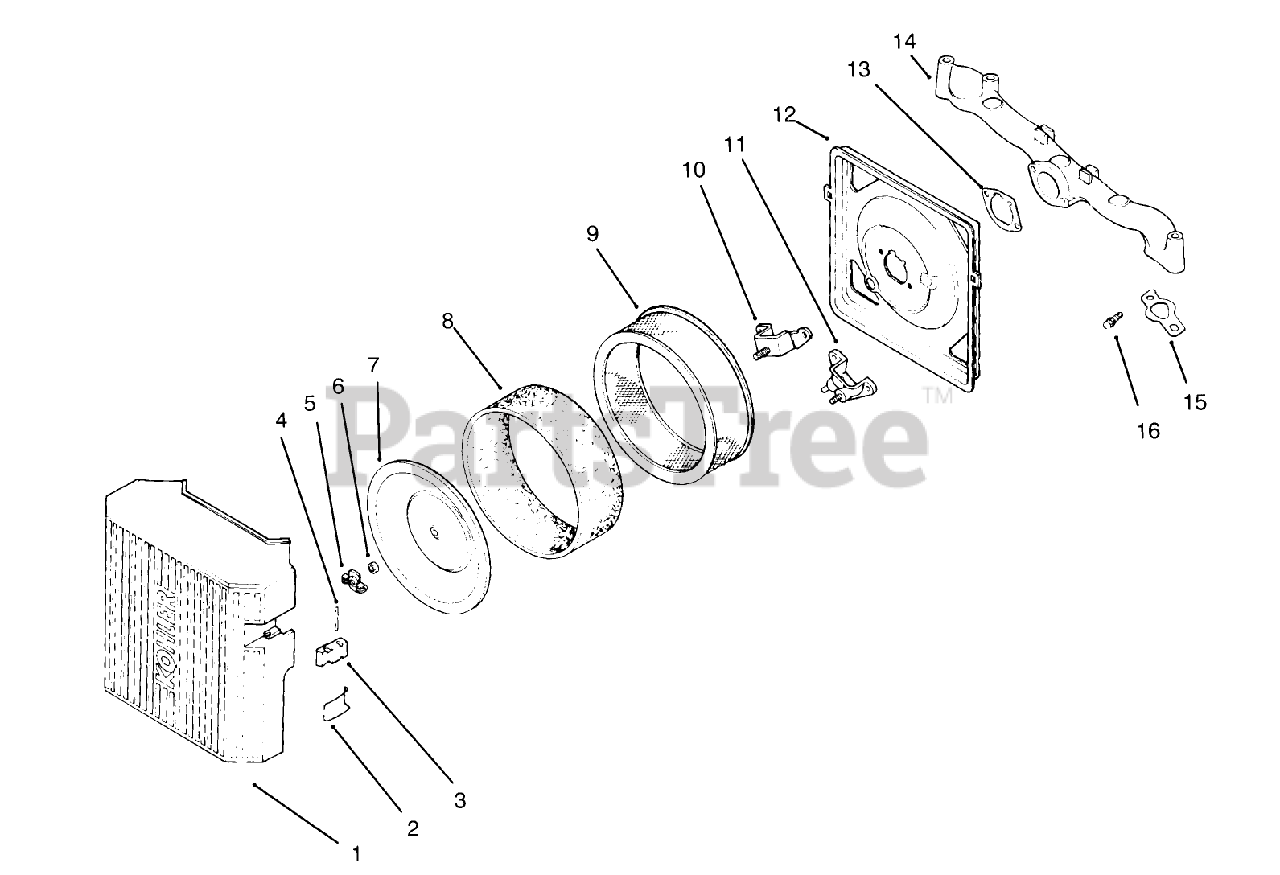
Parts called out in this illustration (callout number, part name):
1	Kit-A/C Cover INCL 2-4 (Only On: 72103;
2	Spring-Latch (Only On: 72103)
3	Latch-Lever (Only On: 72103)
4	Pin-Latch Lever (Only On: 72103)
5	Nut-Wing
6	Seal-Air Intake (Only On: 72103)
7	Cover-Inner Air Cleaner
8	Element-Precleaner
9	Element-Air Cleaner
10	Cup-Fuel Spitback (Only On: 72103)
11	Gasket-Fuel Spitback Cup (Only On: 72103, 72083)
12	Base-Air Cleaner (Only On: 72103)
13	Gasket-A/C Base (Only On: 72103, 72083)
14	Manifold-Intake (Only On: 72103)
15	Gasket-Intake Manifold
